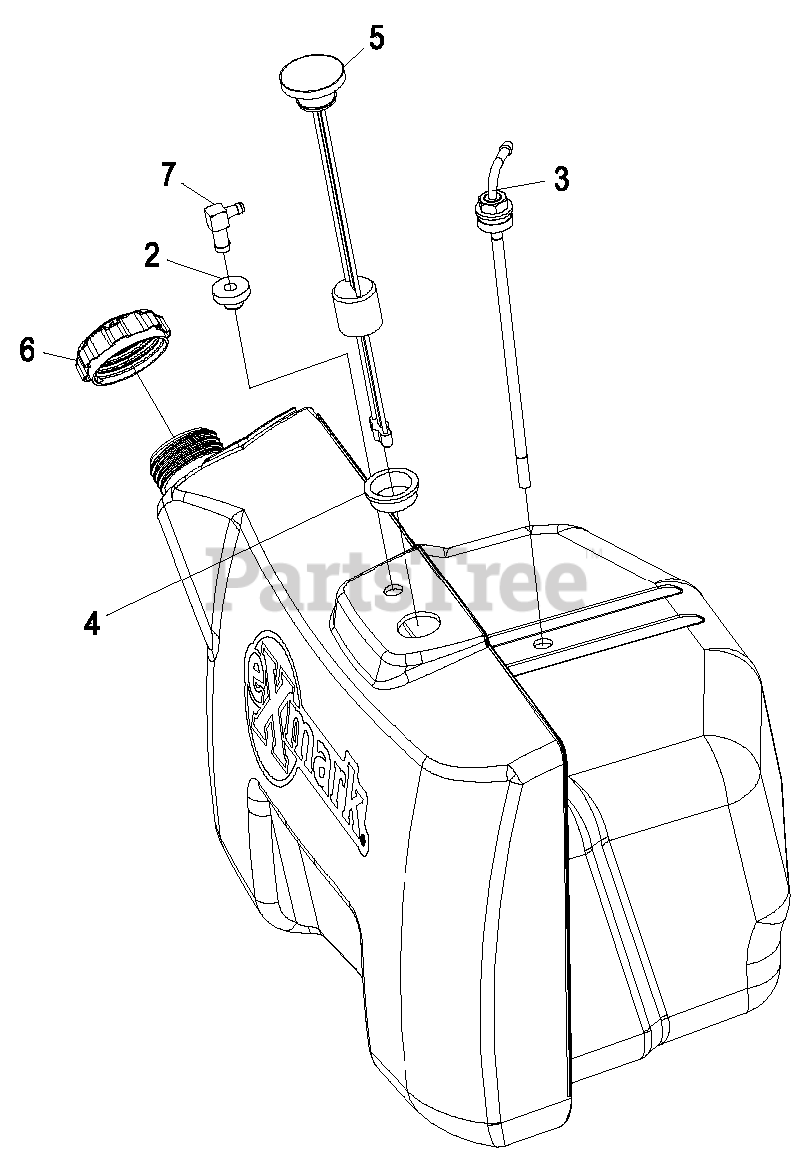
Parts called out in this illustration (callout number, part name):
2	BUSHING
3	FITTING-FUEL, BULKHEAD
4	CONTACT ORDER SERVICES
7	ELBOW-90 DEG
